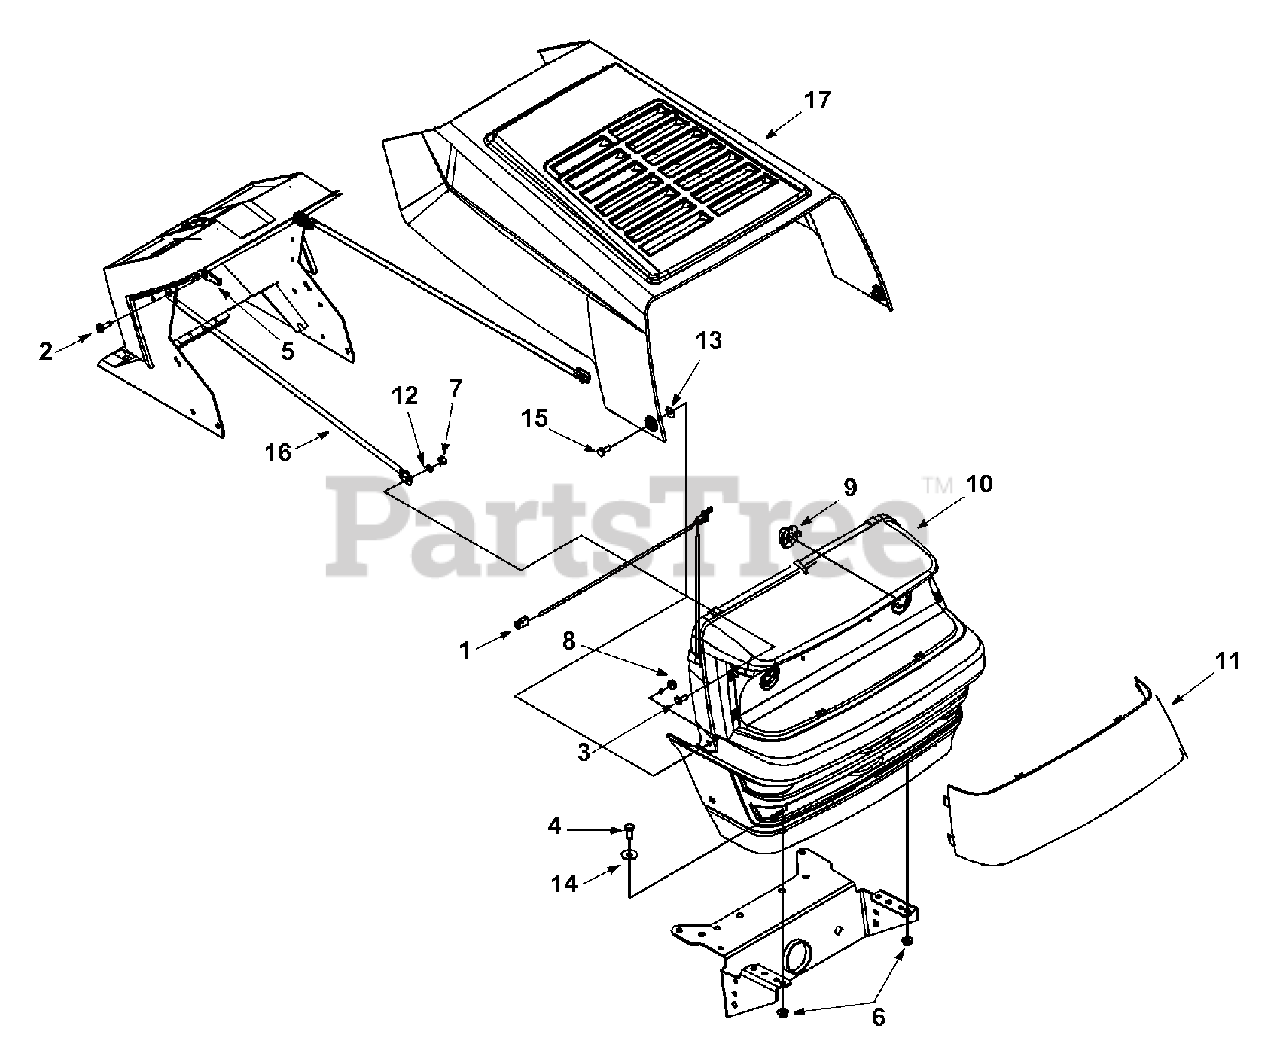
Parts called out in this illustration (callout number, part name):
1	Harness Assembly
2	Hex TT-Tap Scr. 1/4-20 x .75" Lg.
3	Hex Bolt 1/4-20 x .62" Lg.
4	Hex Bolt 5/16-18 x .75" Lg.
5	Speed Nut 1/4-20 Thd.
6	Flange L-Nut 5/16-18 Thd.
7	Hex Nut 1/4-20 Thd.
8	Hex Flange L-Nut 1/4-20 Thd.
9	Socket
10	Grille
11	Lens
12	L-Wash. 1/4" I.D
13	Fl-Wash. .293" I.D. x .75" O.D.
14	Fl-Wash. .349" I.D. x .063" O.D.
15	Shldr Screw .375" I.D. x .125" O.D.
